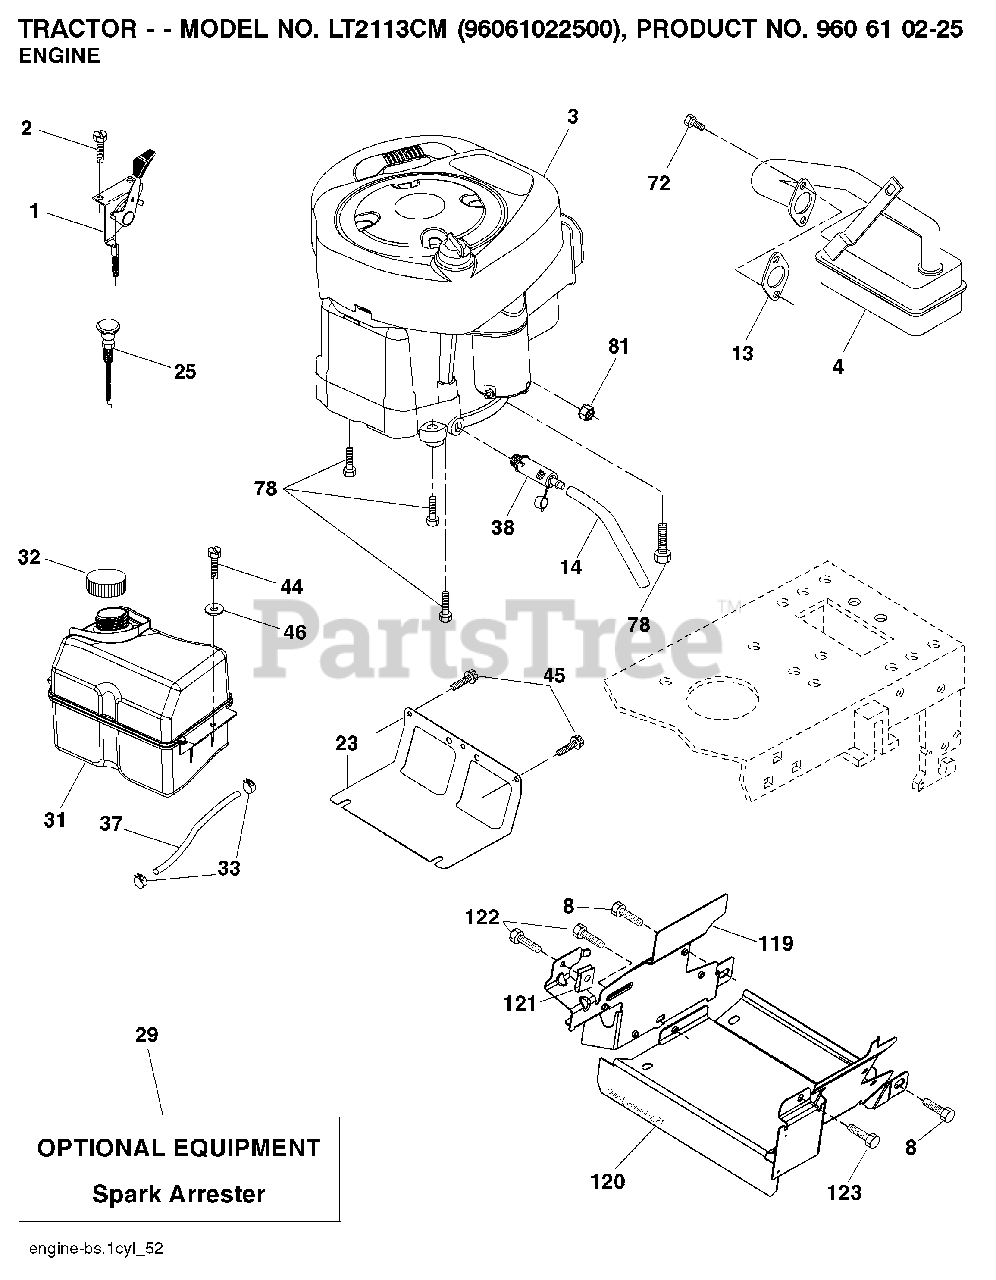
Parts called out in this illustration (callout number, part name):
1	CONTROL TH/CH FLAG
2	SCREW
8	BOLT, 5/16-18 X 1 3/4
13	REPL BY 532 27 22-93
14	TUBE, DRAIN OIL ASM.
23	SHEILD.BROWNING.DBR.GUARD
29	ARRESTER SPARK (OPTIONAL)
31	TANK FUEL
32	FUEL CAP
33	HOSE CLAMP
37	LINE.FUEL.20
38	PLUG DRAIN OIL EASY
44	SCREW HEXWSHR 1/4-20X3/4
45	SCREW, 3/8-16X3/4
46	WASHER
72	SCREW.SOCKET HD.5/16-1
78	SCREW.3/8-16
81	NUT
122	SCREW.1/4-20X5/8
123	SCREW, 5/16-18 X 1/2
